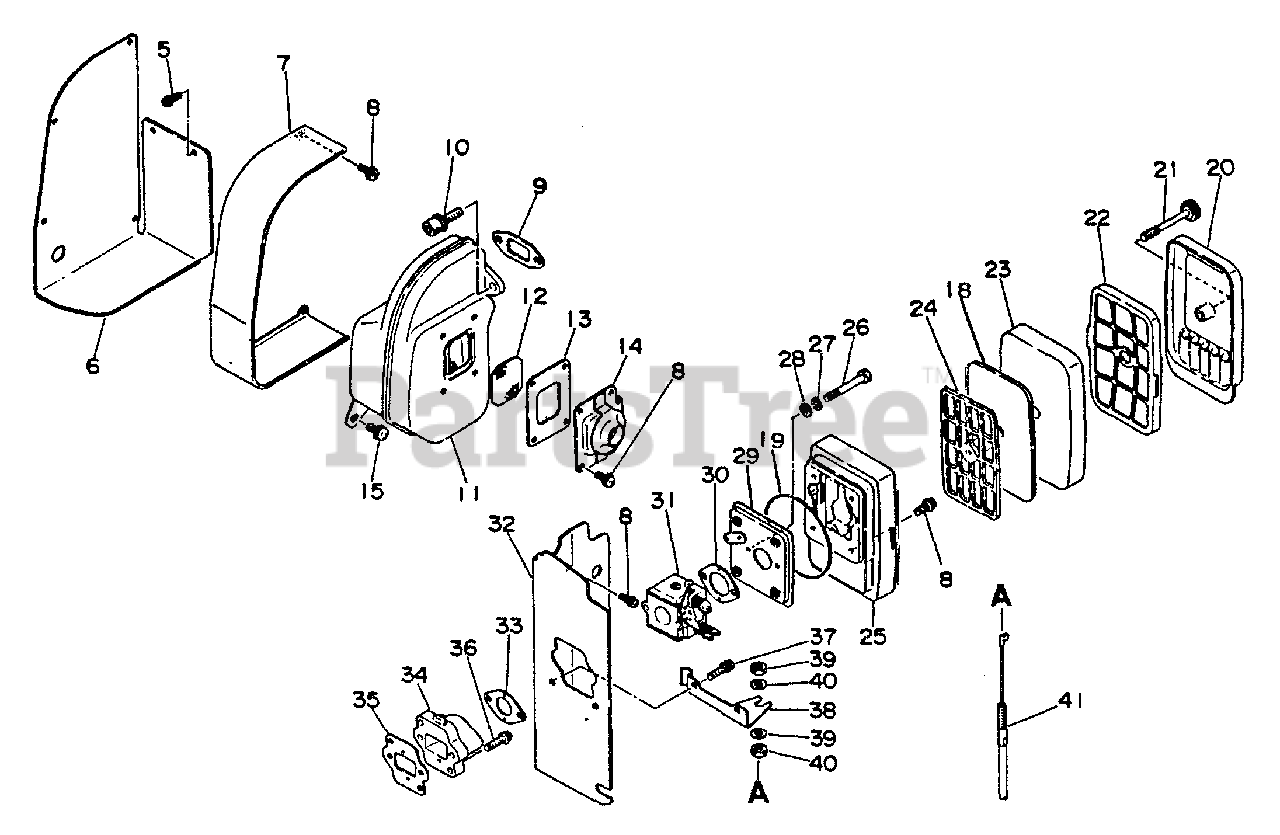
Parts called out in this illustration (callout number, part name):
5	SCREW - 4X14
6	INSULATOR
7	COVER, MUFFLER
8	SCREW - 4X10
9	GASKET, EXHAUST
10	SCREW - 6X20
11	MUFFLER
12	SCREEN, SPARK ARRESTOR
13	GASKET, EXHAUST
14	GUIDE, EXHAUST
15	SCREW - 5X16
18	FILTER, AIR
19	O-RING
20	COVER, AIR FILTER
21	WINGNUT
22	RETAINER, AIR FILTER
23	FILTER, AIR
24	RETAINER, AIR FILTER
25	CASE, AIR FILTER
26	BOLT
27	LOCKWASHER - 5
28	WASHER - 5
29	BRACKET
30	GASKET, INTAKE
31	CARBURETOR C1U-K17
32	INSULATOR
33	GASKET, INTAKE
34	INSULATOR, INTAKE
35	GASKET, INTAKE
36	SCREW - 5X25
37	SCREW - 5X20
39	WASHER - 6
41	CABLE, THROTTLE
